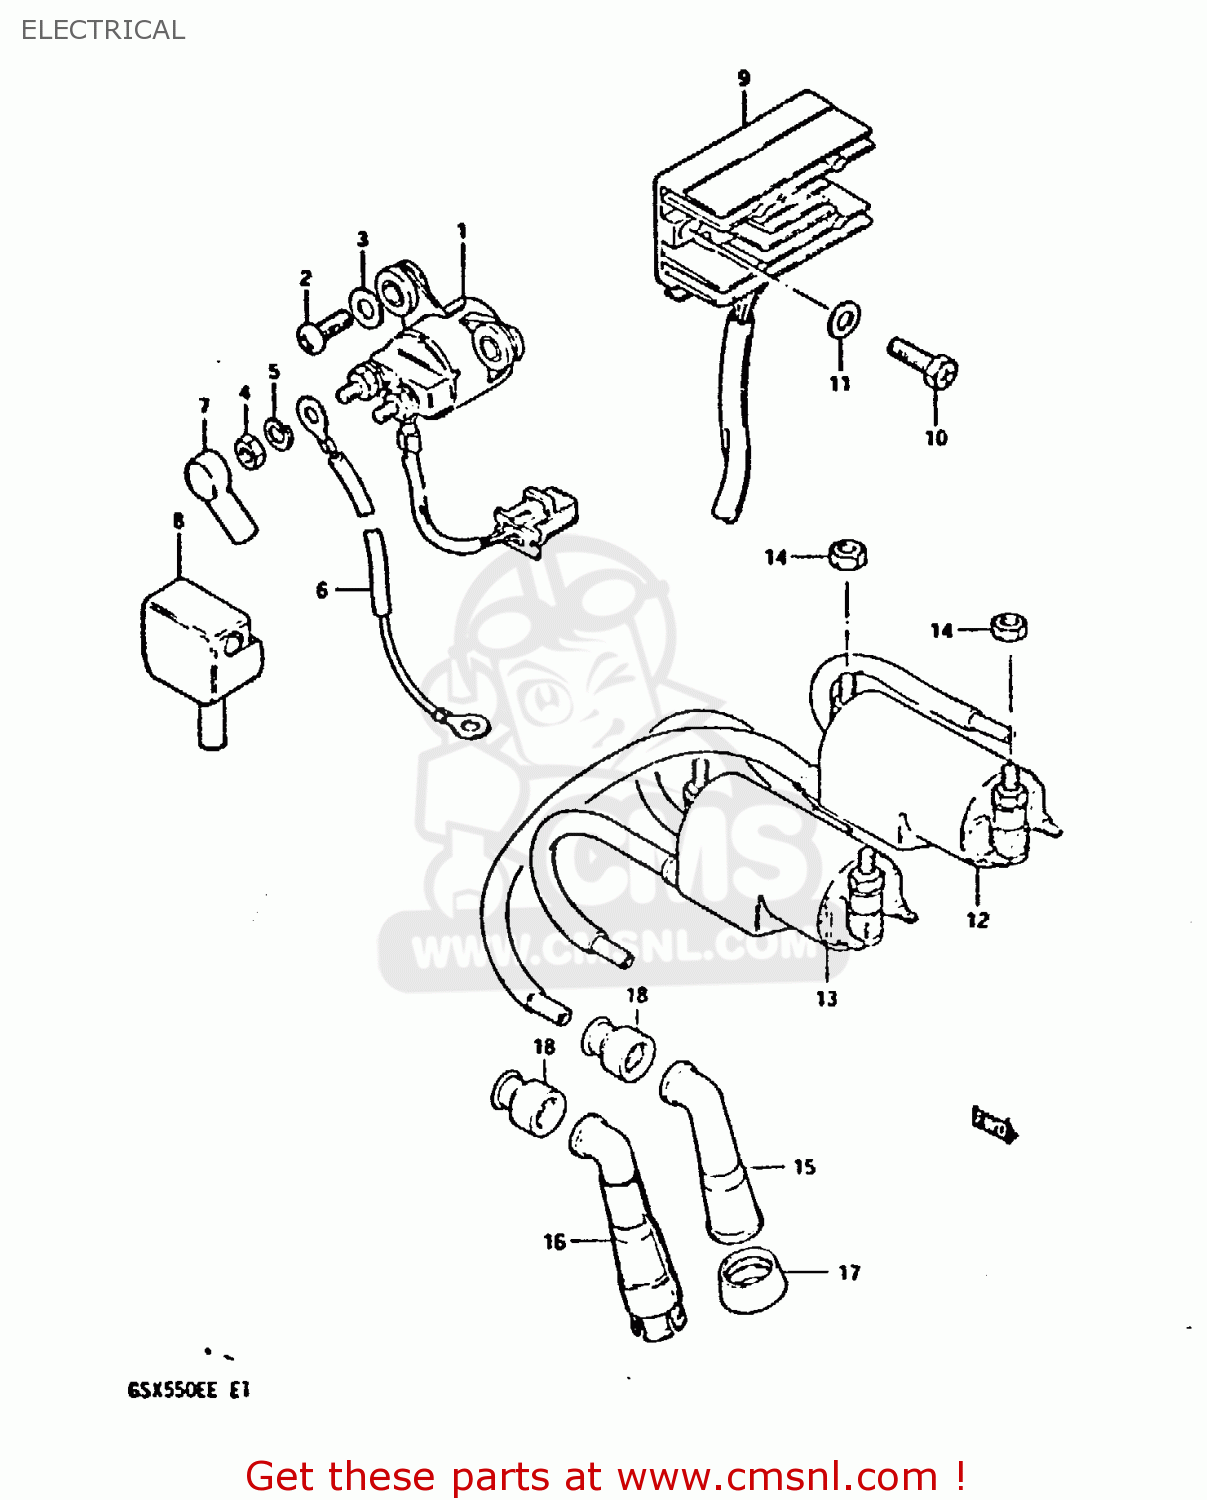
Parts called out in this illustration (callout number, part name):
1	RELAY,STARTER SWITCH
2	SCREW
3	WASHER
4	NUT
5	WASHER,LOCK
6	WIRE,STARTER MOTOR LEAD
7	CAP,STARTER MOTOR TERMINAL
8	CAP,STARTER RELAY TERMINAL
9	RECTIFIER ASSEMBLY
10	BOLT(6X20)
11	WASHER
12	COIL ASSEMBLY,IGNITION
13	COIL ASSEMBLY,IGNITION
14	NUT
15	CAP ASSY,SPARK PLUG
17	SEAL,SPARK PLUG
18	SEAL,SPARK PLU
